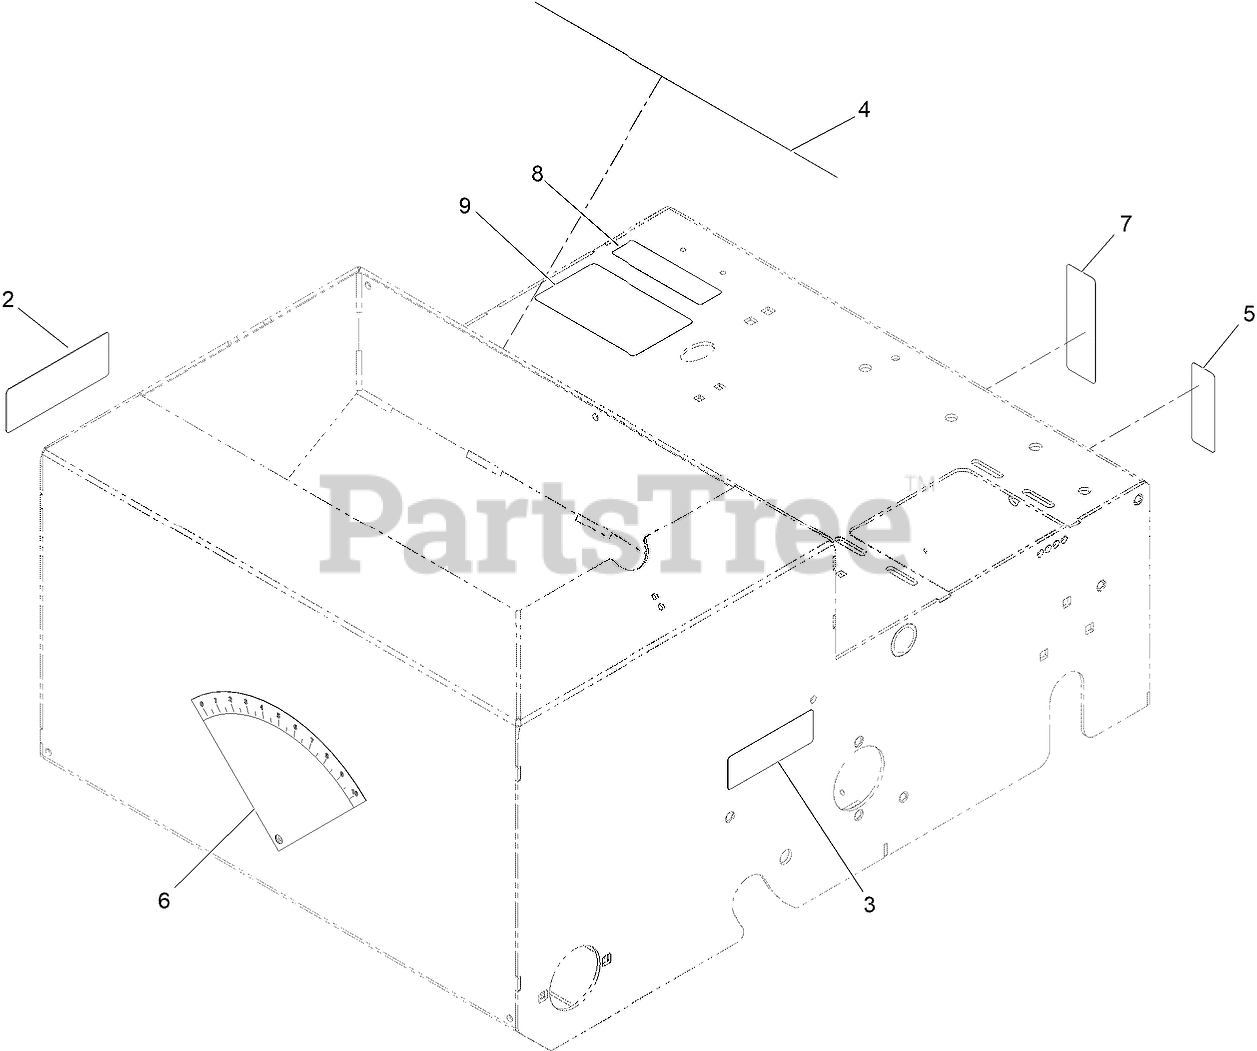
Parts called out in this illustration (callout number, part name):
2	DECAL-DANGER
3	DECAL-WARNING
4	DECAL-WARNING
5	DECAL-BRAKE, PARKING
6	DECAL-FLOW, SEED
7	DECAL-BYPASS
8	DECAL-ARRESTOR, SPARK
9	Decal-Service Aid Seeder
